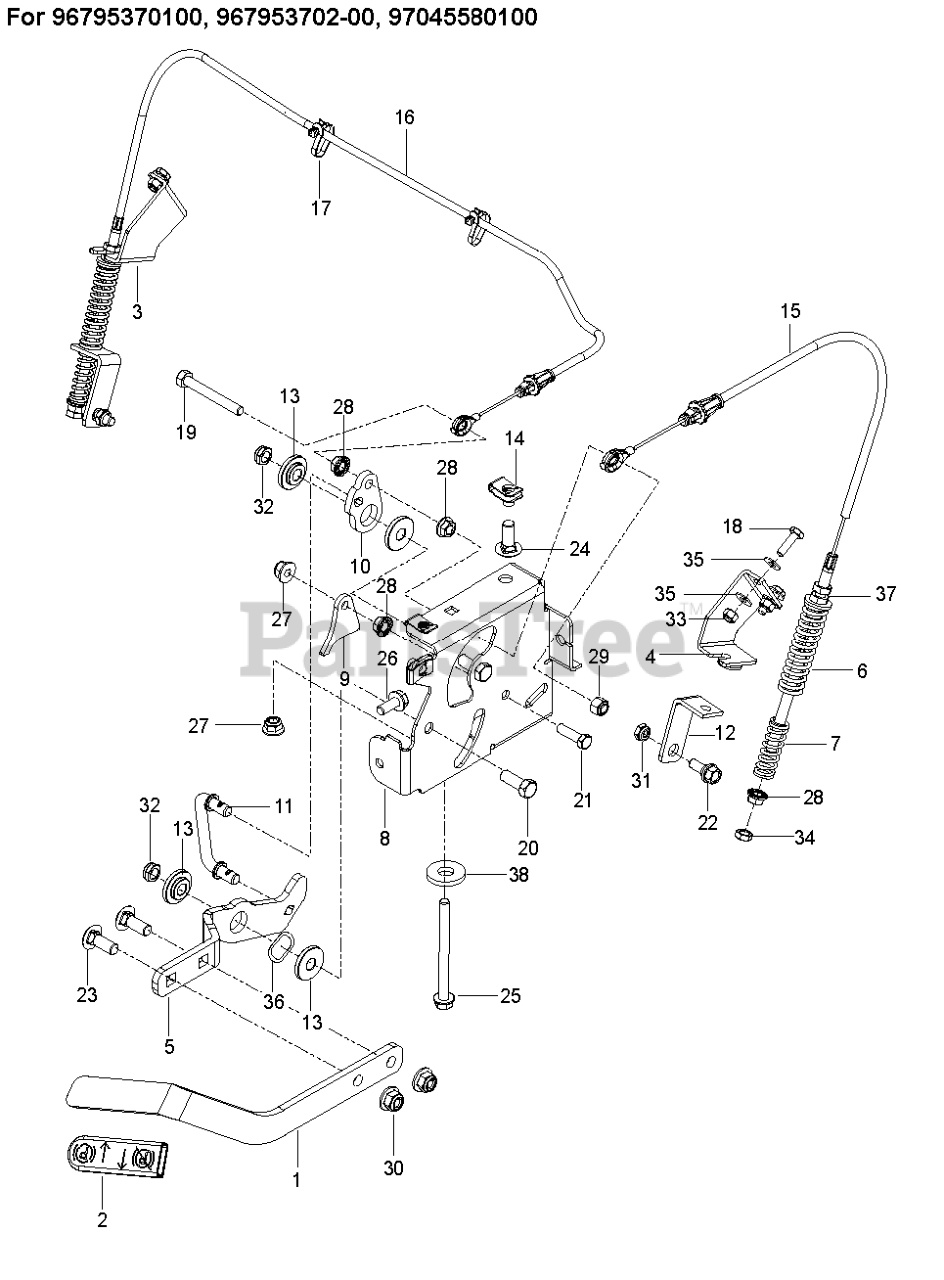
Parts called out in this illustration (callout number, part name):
1	ARM, BRAKE
2	GRIP, PARK BRAKE
3	BRKT, BRAKE RT, BLK
4	BRKT, BRAKE LT, BLK
5	LEVER.PNT.BRAKE.E-DIP
6	SPRING, RETURN
7	SPRING, ENGAGEMENT
8	MOUNT.BRAKET.PNT.BLACK.MS431
9	ACTUATOR, SWITCH
10	BELLCRANK, BRAKE
11	LINKAGE, BRAKE
12	BRKT, BRAKE, BLK
13	BUSHING, BRAKE
14	U-CLIP 5/16-18 NUT RETAINER
15	CABLE.ASSY.BRAKE.CABLE.SHORT
16	CABLE.ASSY.BRAKE.CABLE.LONG
17	TIE WRAP, 8-3/8", W/CLIP
18	HCS 1/4-20X7/8 GR5
19	HCS 5/16-18 X 2 1/2 TPBLT
20	HCS 3/8-16X1.GRD.5.ZD
21	HCS 5/16C X 1
22	BOLT, SHOULDER
23	RHSNB 3/8C X 1
24	BOLT 5/16C X 3/4" CARRIAGE
25	HHFS 5/16-18 X 3 3/4
26	HHFS 5/16-18 X 3/4
27	5/16-18 NYLOC FLANGE NUT
28	NUT 5/16C WHIZ
29	NUT 5/16 NYLOC
30	NUT 3/8-16 HEX FLG NYLOC ZD
31	5/16-18 THIN PROF NY
32	NUT HEX 3/8-16 NYLON, THIN
33	NUT.1/4-20.HEX.NYLOC.ZD
34	NUT 5/16-18 HEX JAM ZD
35	WASHER 1/4 SAE
36	WASHER, .825 X 1.087, WAVE
37	WASHER 3/8 SAE FLAT
38	WASHER.9/16 X 1 3/8 X 12 GA.
